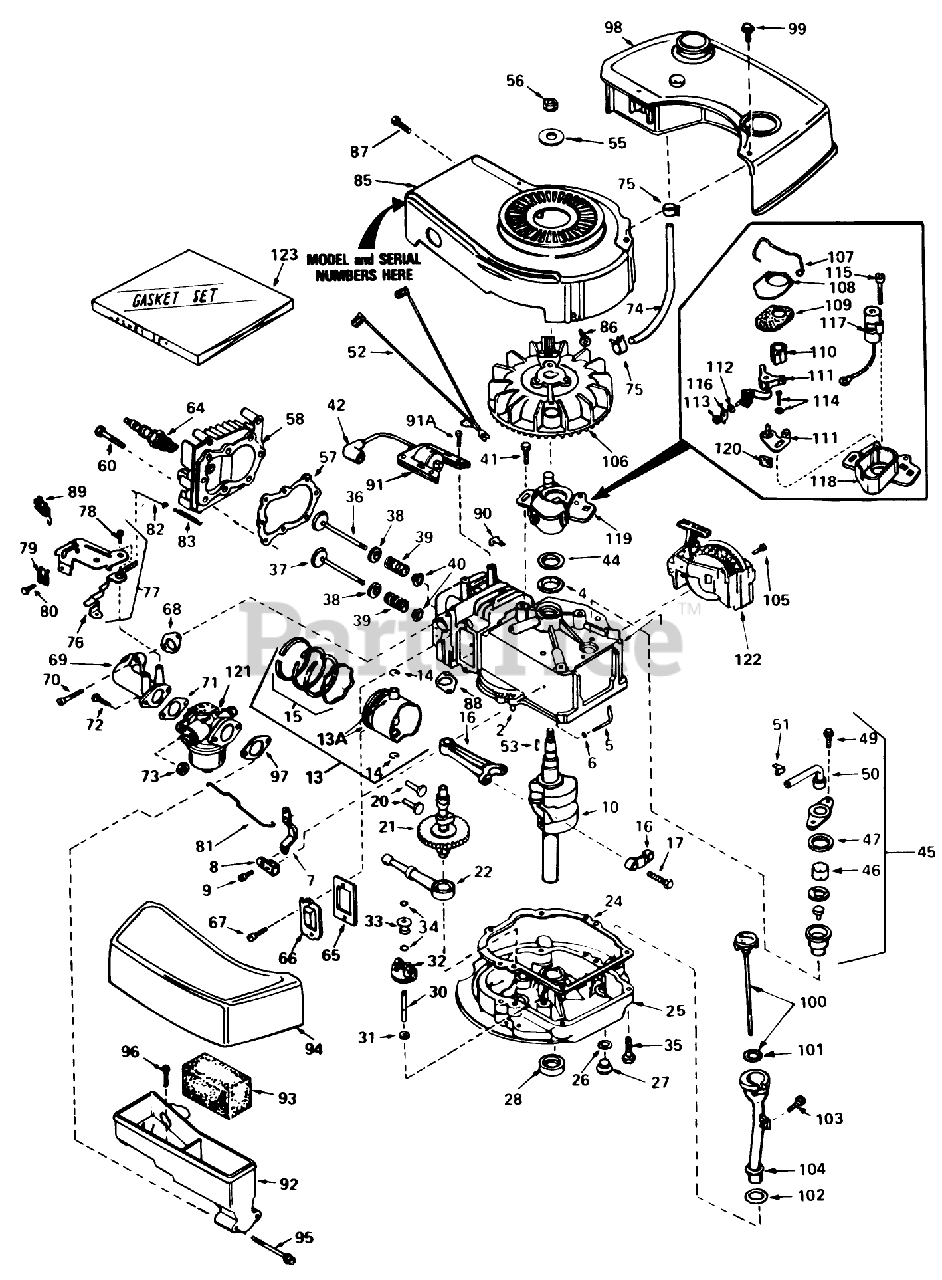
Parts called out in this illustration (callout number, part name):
1	Cyiinder Assy. (Incl. Ref. #2, 4 105)
2	Pin-Dowel
4	Seal-Oil
5	Rod, Governor (Incl. No. 36)
6	Washer-Flat
7	Governor Lever
8	Clamp-Lever, Governor
9	Screw
10	Crankshaft
13	Piston, Pin Ring Assy. (Std.) (Incl. Ref. #13A, 14 15)
13	Piston, Pin Ring Assy. (.010 oversize) (Incl. Ref. #13A, 14 15)
13	Piston, Pin Ring Assy. (.020 oversize) (Incl. Ref. #13A, 14 15)
13A	Piston Pin Assy. (Incl . Ref. . #14) (Std.)
13A	Piston Pin Assy. (Incl. Ref. #14) (.010 Oversize)
13A	Piston Pin Assy. (.020 oversize) (Incl. Ref. #14)
14	Ring-Retaining, Piston Pin
15	Ring Set (Std.)
15	Ring Set (.020" OS)
15	Ring Set (.010" OS)
16	Rod Assy., Connecting (Incl. Ref. #17)
17	Bolt-Rod, Connecting
20	Lifter-Valve
21	Camshaft(Mech.Comp. Release)
22	Oil Pump ASM
24	Gasket, Mounting
25	Flange Assy., Mounting (Incl. Ref. #26thru 30)
26	Gasket-Oil Drain
27	Plug Oil Drain
28	Seal Oil
30	Shaft-Governor
31	Washer-Flat
32	Governor Gear ASM
33	Spool-Governor
34	Ring-Retaining
35	Screw (1/4-20 x 1-1/4)
36	Valve, Intake (Std.) (Incl. Ref. #40)
36	Valve, Intake (1/32" oversize)(Incl. No. 40)
37	Valve, Exhaust (Std.)(Incl. No. 40)
37	Valve, Intake (1/32" oversize)(Incl. No. 40)
38	Cap-Upper Valve Spring
39	Spring-Valve
40	Cap-Valve, Spring
41	Screw
42	Cover-Spark Plug
44	Gasket Stator
45	Breather Assy. (Incl. Ref. #46 thru 51)
46	Element-Breather
47	Gasket-Breather
49	Screw (10-24 x 9/16)
50	Tube, Breaker
51	Clip, Breather
52	Wire Ground
53	682488 LB GRASS HI-
55	Washer-Belleville
56	Nut-Flywheel
57	63573 GIL 42 SNWTHW
58	Head-Cylinder
60	Screw (5/16-18x1-1/2)
64	Plug, Spark (J17LM or equiv.)
64	Plug, Spark (Champion RCJ-8)
65	Gasket-Breather
66	Cover-Valve
67	Screw
68	Gasket-Intake
69	Pipe, Intake (Incl. No. 68)
70	Screw (1/4-20 x 1)
71	Gasket-Carburetor
73	Nut and Lock Washer (1/4-28)
74	Line-Fuel
75	Clamp-Line, Fuel
76	Lever Control
77	Control Assy., Speed (Incl. Nos, 76, 78 89)
78	Screw, Hex Washer Hd Shoulder Self-Tap
79	Conduit
80	Screw (10-32 x 3/8)
81	Link-Throttle
82	Link Governor Spring
83	Spring Governor
85	Housing Blower
86	Screw
87	Screw (10-24 x 9/16)
88	Gasket Exhaust
89	Terminal
90	Clip-Wire
91	Lamination Coil Assy. (Incl. No. 42)
91A	Screw
92	Body Air Cleaner
93	Filer, Air
94	Cove, Air Cleaner
95	Screw Fil Hd.
96	Screw, Hex Hd.
97	Gasket-Air Cleaner
98	Tank, Fuel
99	Screw (10-32 x 35/64)
100	Dipstick, Oil (Incl. Ref. #101)(Twist Lock)
101	O-Ring
102	Gasket
103	Screw (10-32 x 1/2)
104	Tube-Oil Fill
105	Screw (1/2-20x5/8)
106	FIywheel
107	Spring Breaker Box
108	Cover-Dust
109	Gasket-Dust Cover
110	Cam-Breaker
111	Breaker Assy.
112	Washer
113	DECAL
114	Breaker Screw
115	Condenser Screw
116	Terminal, Ground
117	Condenser
118	Stator Plate
119	Stator Plate Assy. (incl. Nos. 107, 111 thru 118 120)
120	Felt,Cam Wiper
121	Carburetor (Incl. Ref. #71 )
122	Starter-Sidemount
123	Gasket Set
